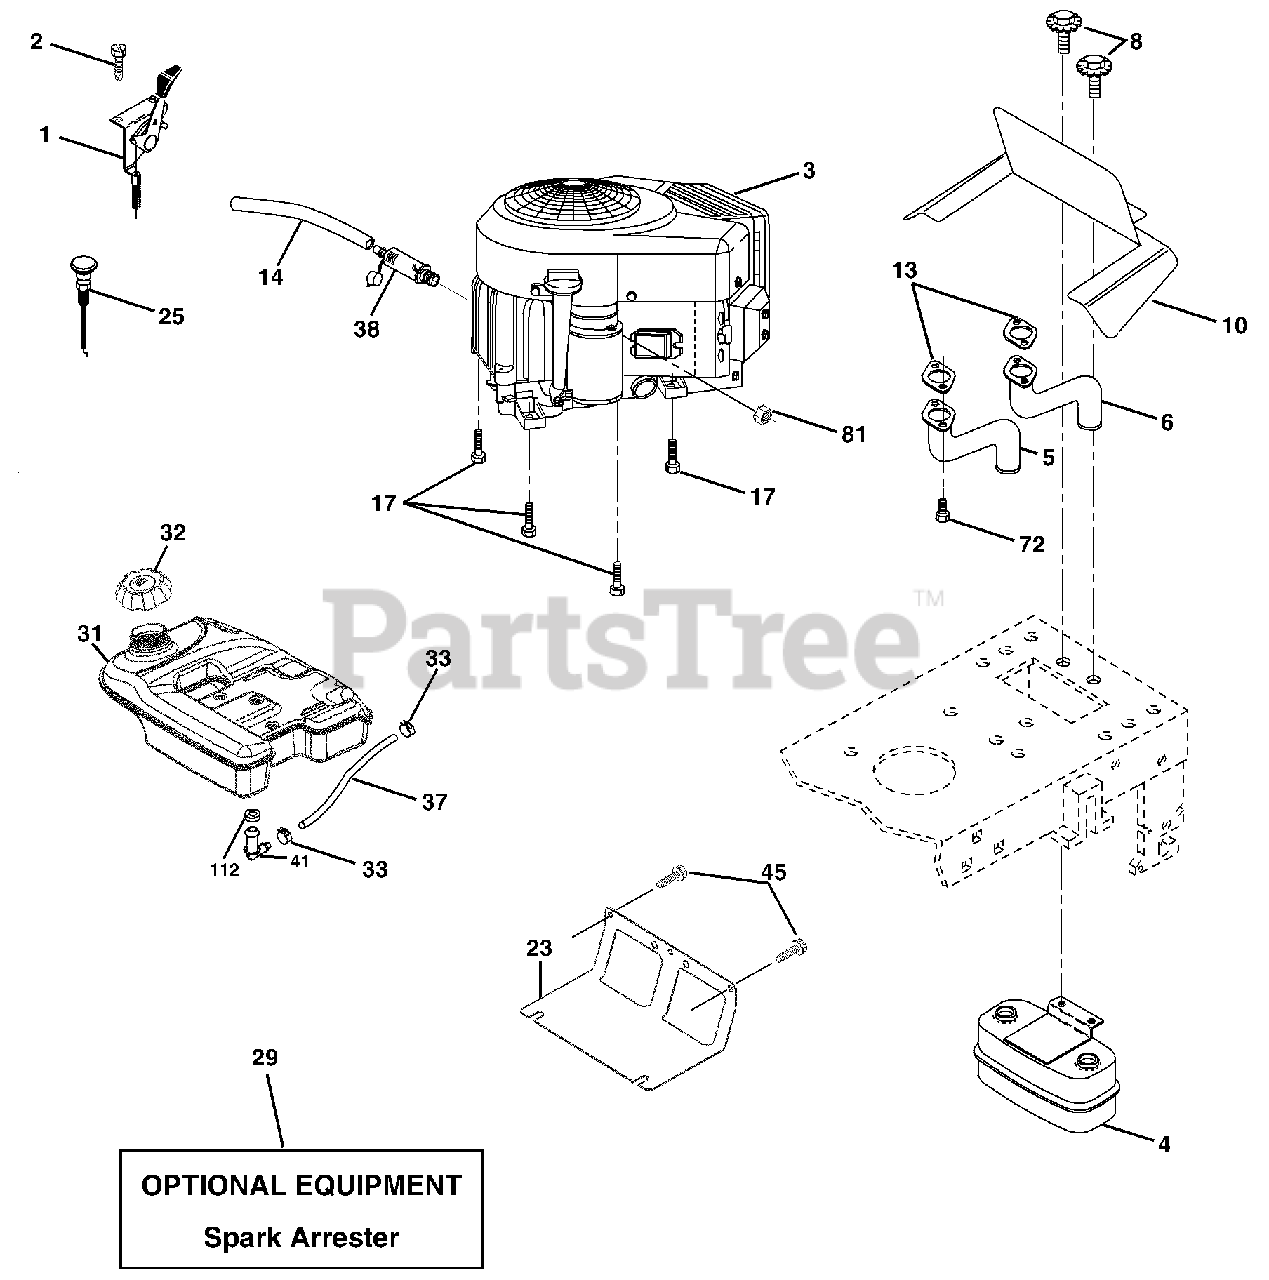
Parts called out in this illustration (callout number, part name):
1	Control, Throttle
2	Screw Hex Thd Cut 1/4-20 x 1/2
4	Muffl er, Asm. Twin Lo-Tone
5	Pipe Exhaust Intek 20 RH
6	Pipe Exhaust Intek 20 LH
8	Bolt 5/16-18 unc x 3/4 w/Sems
10	Shield Browing B&S Intek II
13	Muffl er Gasket
14	Tube Oil Drain
17	Screw 3/8-16 x 1-1/2
23	Shield, Browning/Debris Guard
25	Control Choke
26	Nut Keps 3/8-24 unf
29	Arrester, Spark
31	Tank, Fuel
32	Cap Gauge, Fuel
33	Clamp, Hose Blk
37	Line, Fuel
38	Plug Drain Oil Easy
41	Stem Tank Fuel
45	Screw Hex Wsh Thdrol 3/8-16 x 3/4
72	Screw Socket Head 5/16-18 x 1
81	Nut Keps Hex 1/4-20 unc
112	Bushing
